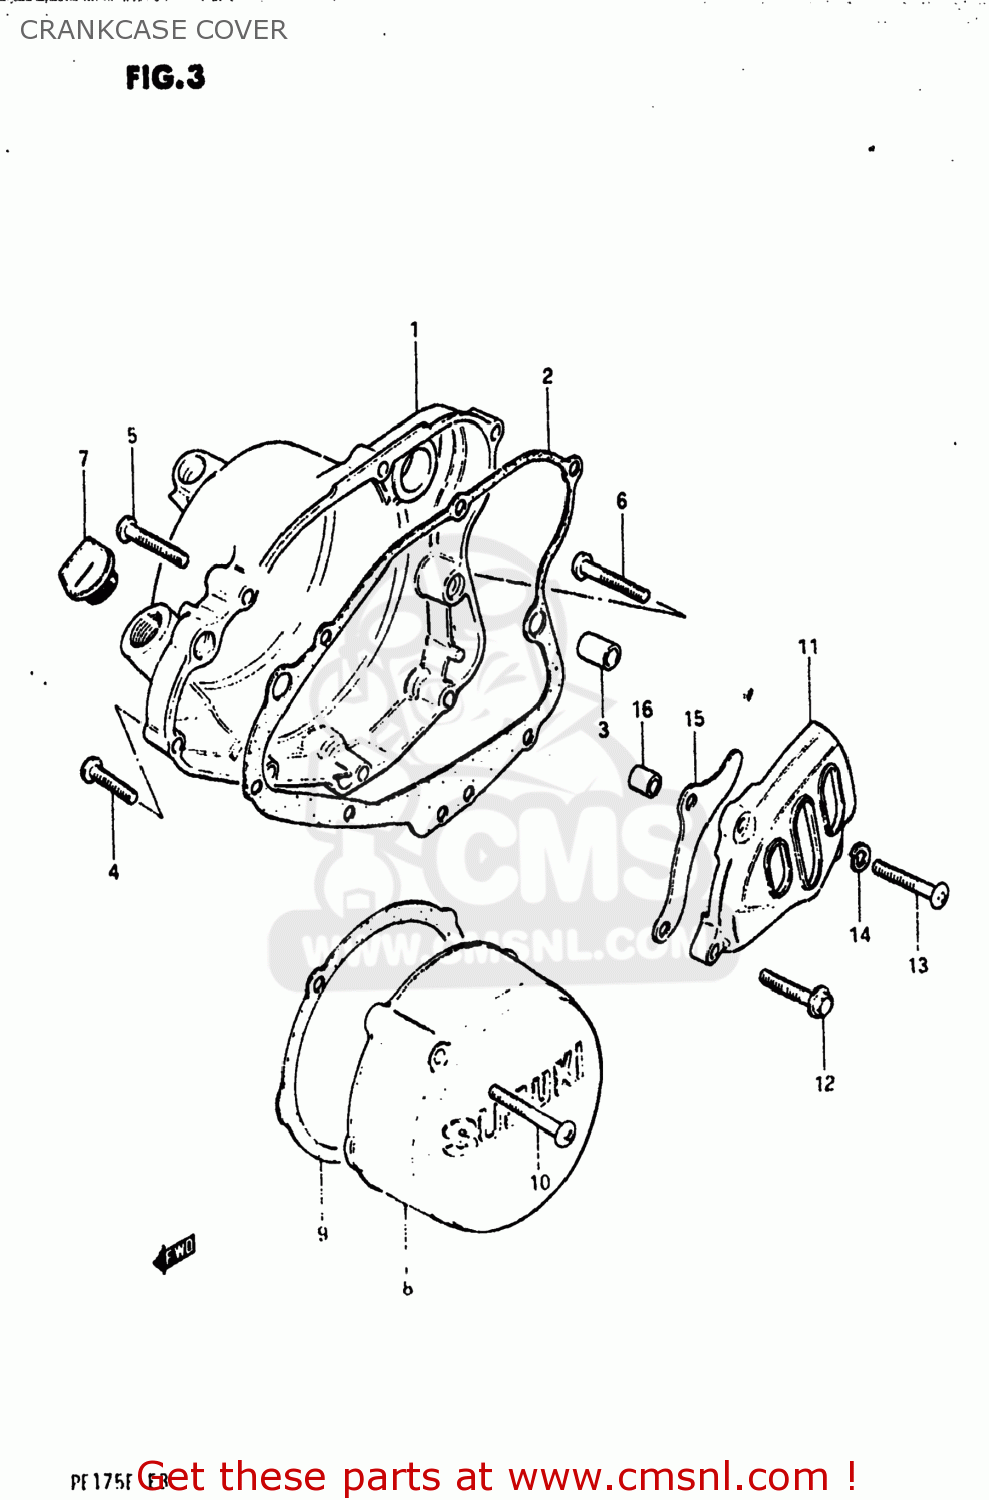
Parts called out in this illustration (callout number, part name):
1	COVER,CLUTCH
2	GASKET,CLUTCH COVER (MCA)
3	PIN
4	SCREW
5	SCREW
6	SCREW
7	PLUG,OIL FILTER
8	COVER,MAGNETO
9	GASKET,MAGNETO COVER (NAS)
10	SCREW
11	COVER,ENGINE SPROCKET
12	BOLT
13	SCREW
14	LOCK WASHER
15	PLATE,FRONT CHAIN GUIDE
16	SPACER(6.5X10.5X12)
